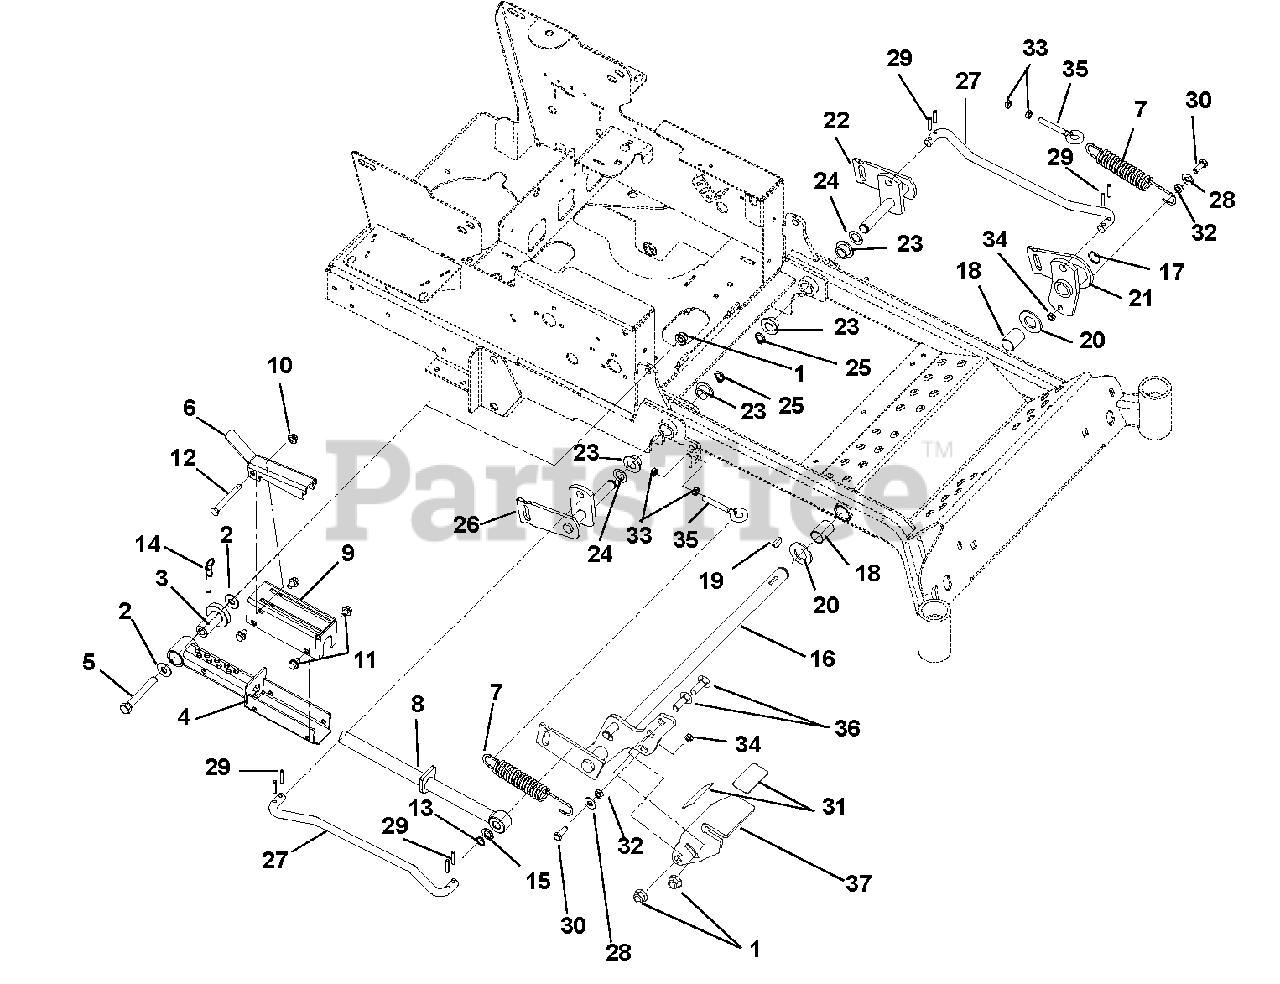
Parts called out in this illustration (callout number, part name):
1	@NUT-LK-NYL-FLG .50-13 YWZC
2	WSHR-FL-STL .531X1.250X.10 YWZ
3	BEARING, PEDESTAL
4	WMT, MECHANICAL LIFT
5	@BLT-HEX .50-13X3.75 GR5 YWZC
6	LOCK-UP, MECH LIFT
7	SG-TENS .162X1.25X8.25 WLD 25
8	WMT, MECH. LIFT SHAFT (.62)
9	WMT, MECH LIFT COVER
10	@NUT-LK-NYL-FLG .38-16 YWZC
11	@SCR-TAP .38-16X.50 HWH TR YWZ
12	@BLT-HEX .38-16X3.25 GR5 YWZC
13	RG-RTNG-EXT .625X.050
14	PIN, SPRING BALL .375OD X 1.50
15	WSHR-FL-STL .630X1.005X.062 YZ
16	WMT,DECK LIFT,ADJ FOOT PEDAL
17	RG-RTNG-EXT 1.00X.078
18	BSHG,1.00ID X 1.125OD X 1.50LG
19	KEY-WDRF .25X1.00 HRD #15
20	WSHR-FL-STL- 1.062X2.0X.134 YZ
21	WMT, LH FRONT MOWER LIFT
22	WMT, LH REAR LIFT ARM (100)
23	BSHG-FLG .762X1.0X.580X1.48 NY
24	WSHR-HDND-THRST .758X1.23X.031
25	RG-RTNG-EXT .689X.078
26	WMT, RH REAR LIFT ARM (100)
27	ROD-LIFT ASSIST 16.35"
28	@WSHR-FL-STL.438X1.00X.083 YWZ
29	PIN-ROLL .250X1.25 STNLESS STL
30	@BLT-HEX .38-16X1.00 GR5 YWZC
31	GRIP, PEDAL 1.50 X 3.00
32	BSHG-SLV .377X.624X.235
33	NUT-HEX-JAM .375-16 YWZC
34	@NUT-LK-CTR-JAM .375-16 YWZC
35	BLT-EYE .375-16X2.50 YWZC
36	@BLT-RDHDSQNK .50-13X1.50 G5YZ
37	ADJUSTABLE FOOT LIFT PEDAL-BLK
